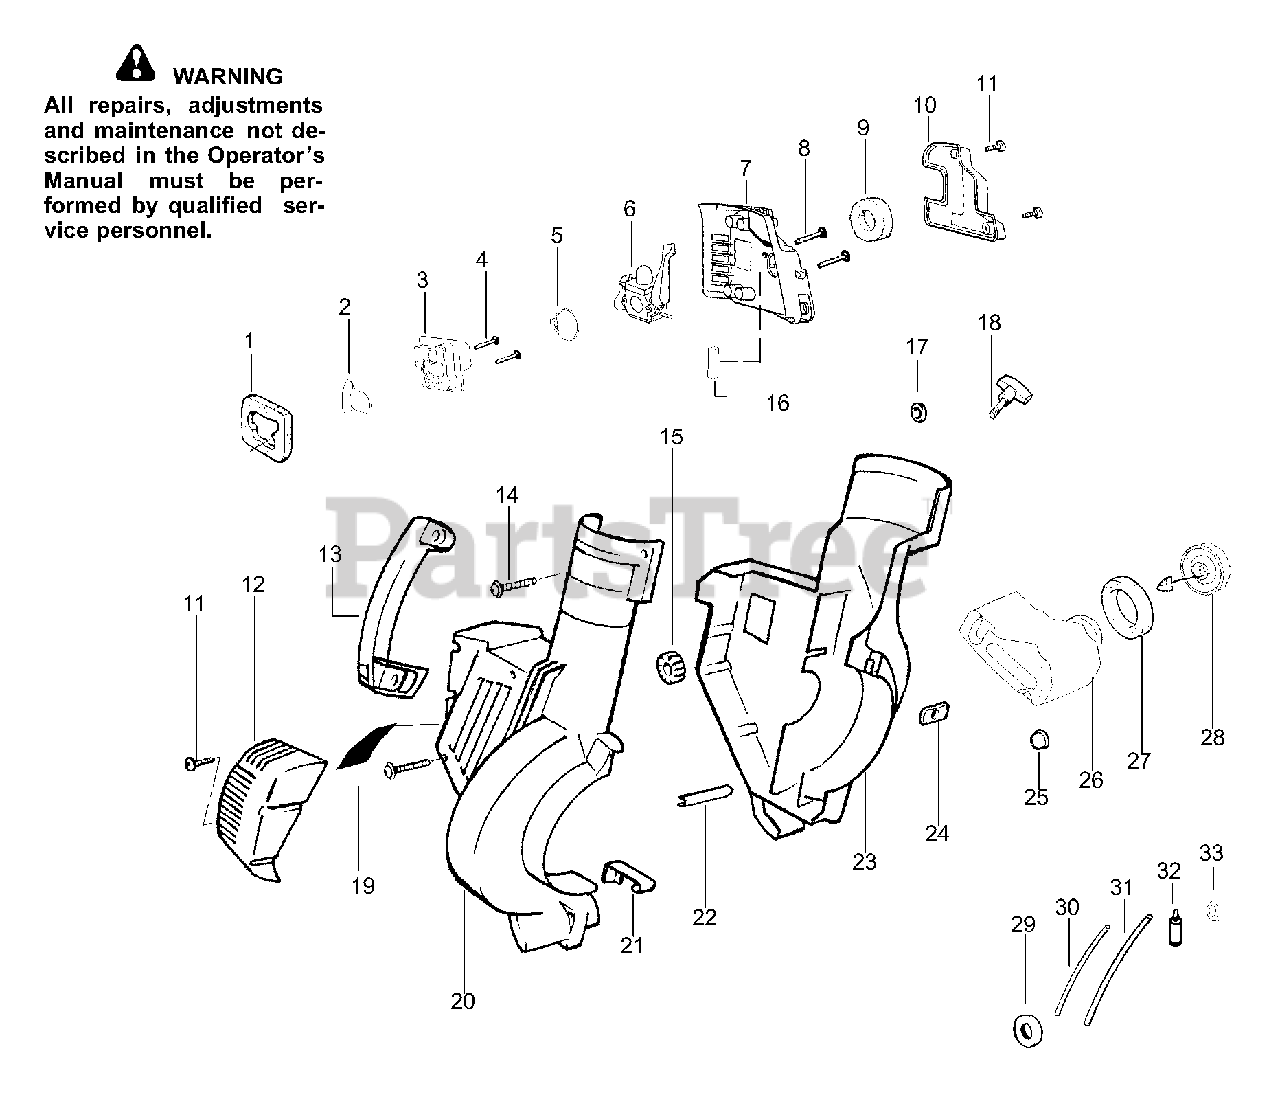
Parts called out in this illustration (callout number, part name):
1	Air Dam (kit)
2	Gasket-Adapter (kit)
3	Carburetor Adaptor
5	Gasket-Carburetor (kit)
6	Kit-Carb Ass'y. (C1Q-W11)
6	Kit-Carb Ass'y. (C1Q-W11C)
8	Screw-Carb.
9	Filter-Air
10	Cover-Air Filter
12	Guard-Muffler
15	Isolator
16	Foam 25.4mm (kit)
18	Knob-Tube Clamp
19	Reflector-Heat (kit)
20	Housing-Right
21	Spring-Cover Latch
22	Guide-Starter Rope
23	Housing-Left
25	Isolator-Crankcase
26	Assy-Fuel Tank
27	Gasket-Fuel Tank
28	Fuel Cap w/Retainer
29	Grommet-Shroud
30	Kit-Line Carb/Purge
31	Kit-Line Tank/Purge
32	Assy-Fuel Pick-up
33	Grommet-Fuel line (kit)
